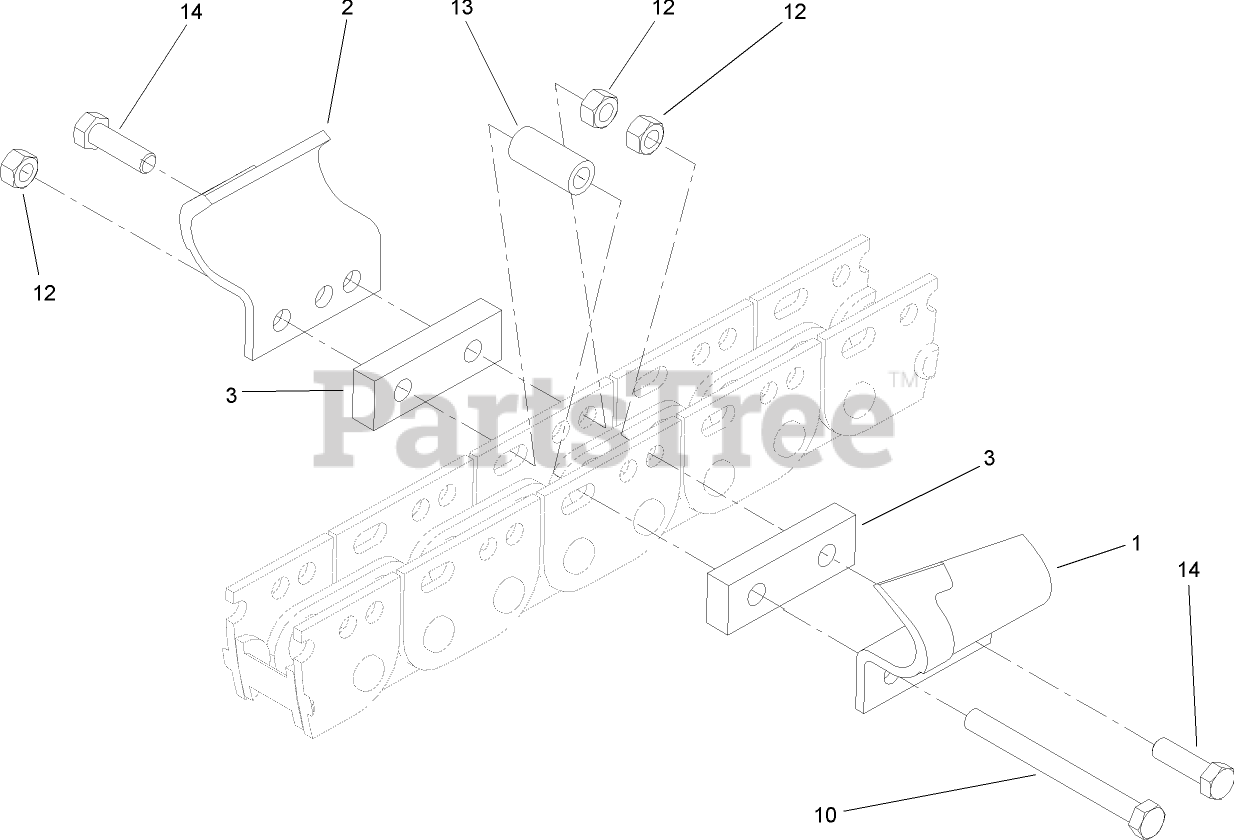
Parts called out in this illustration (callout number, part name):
1	TOOTH-SOIL, LH
2	TOOTH-SOIL, RH
3	SPACER-CUT, 5 INCH
10	SCREW-HH
12	NUT-LOCK
13	SPACER-TUBE
14	SCREW-HH
